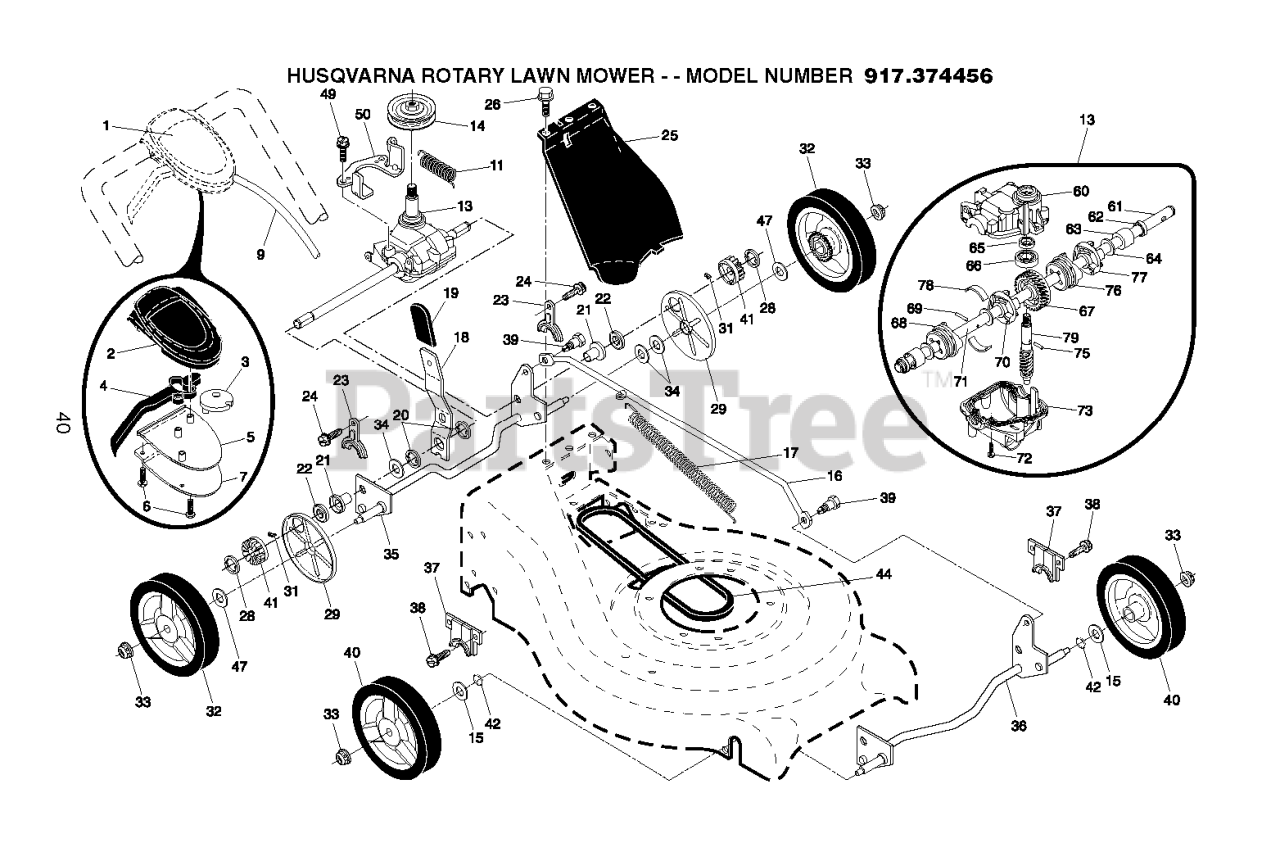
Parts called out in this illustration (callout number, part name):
1	DRIVE CONTROL ASSY, AUTO WALK
2	COVER TOP AUTO WALK CONTROL
3	PULLEY.CAM.DRIVE.CONTROL.EZ
4	LEVER, AUTOWALK DRIVE CONTROL
5	COVER BOTTOM AUTO WLK CONTROL
6	SCREW, PHILLIPS HEAD 10 X 5/8
7	BRACKET.DRIVE.CONTROL.MOUNT.BL
9	CABLE.ASSY.RGD.EZ.AUTO
13	TRANSMISSION.21.RWGD.AUTO.SP
14	PULLEY.1.PIECE
15	WASHER PM
16	ROD.CONNECTING.SPT.BLACK
17	SPRING EXTENSION
18	SPRING.SELECTOR.SPT.21.BZP
19	KNOB.S/P.RWGD.EXT.ERGO.GREY
21	BEARING.ASM.RGD.AUTO.SP
22	BEARING
23	RETAINER DRIVE ASM. STMP.
24	SCREW 14-20 X 5/8
25	COVER.DRIVE.21.RWGD.MO
28	E-RING 7/16 RE
29	COVER.DUST.WHEEL
31	PAWL, DRIVE
32	WHEEL.8X1.75.H3SPK.RAD3.GY
33	NUT.HEX.FLANGE.3/8-16.LO(3 2)
35	SHAFT.ASM.REAR.TORQUE.BZP.8
36	SHAFT.ASM.FRONT.TORQUE.BZP.
37	RETAINER.FRONT.SHAFT
39	SHOULDER BOLT SEMI GIMLET PT.
40	WHEEL.8X1.75.H3SPK.RAD3.GY.BB1
41	PINIION.14.TOOTH.RGD
42	O-RING..070X.487.NEOPRENE
44	BELT.RGD.VS
47	WASHER FLUT
50	BRACKET.BELT.GUIDE.VS.RGD.BZP
60	CASE UPPER
61	SHAFT OUTPUT LONG
62	SEAL.OUTPUT.SHAFT
65	SEAL INPUT SHAFT
67	GEAR 28 TEETH
68	DOG.FIXED.LH.32003
69	PIN 7 33732
70	DOG.MOVEABLE.LH.32005
71	SHAFT OUTPUT SHORT (12294)
73	CASE, LOWER
75	PIN 3.50.337 - 33733
76	DOG.MOVEABLE.RH.32006
77	DOG.FIXED.RH.32004
78	SPRING LEAF
79	SHAFT WORM
